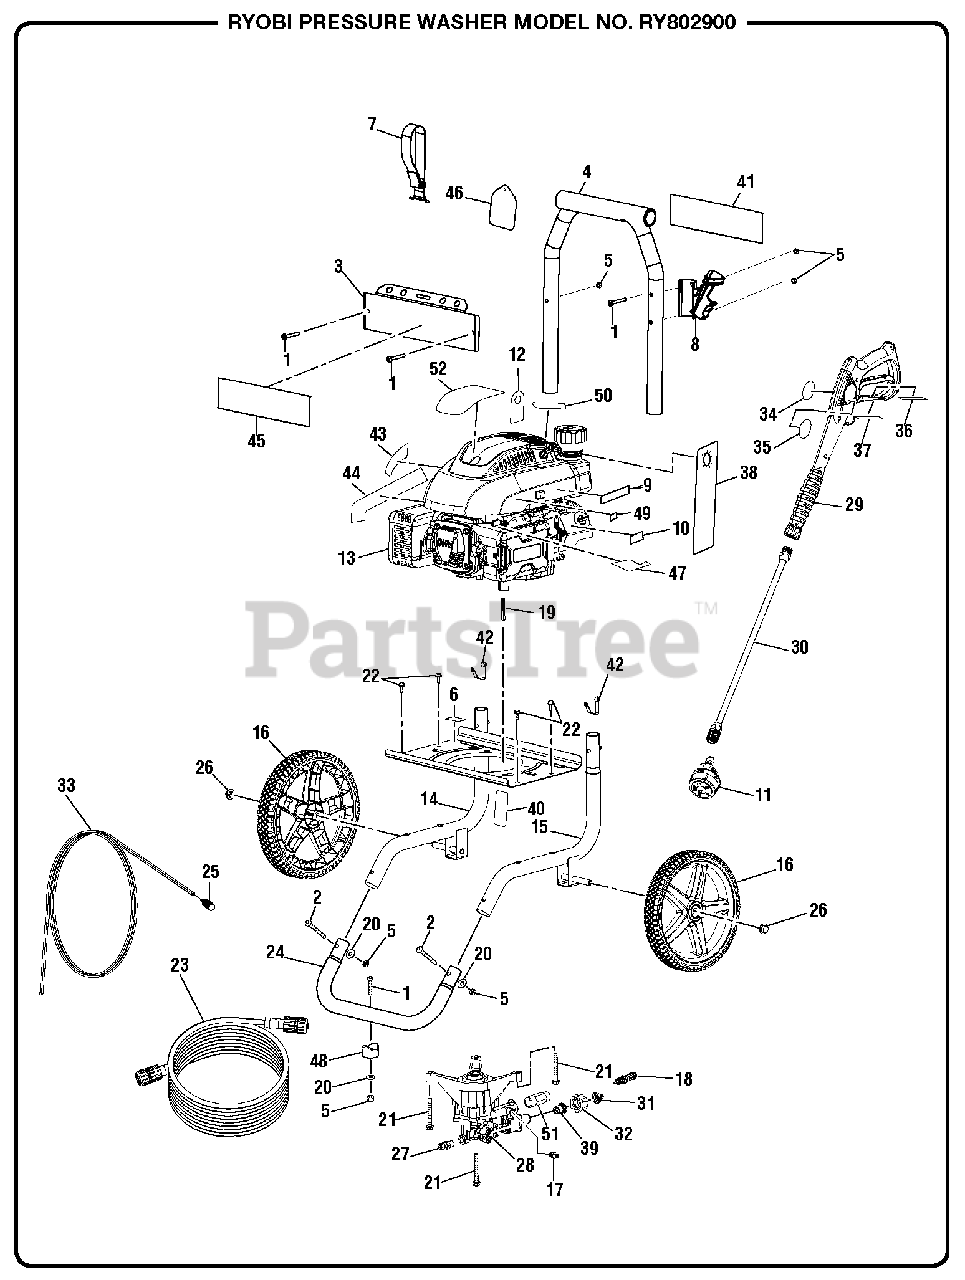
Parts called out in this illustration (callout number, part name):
1	Bolt (M6 x 48 mm, T30 Torx Pan Hd.)
2	Bolt (M6 x 42 mm, T30 Torx Pan Hd.)
3	Performance Panel
4	Handle w/Foam
5	Lock Nut (M6)
6	Add Oil Label
7	Hose Holder Strap
8	Wand Holder
9	Instruction Label
10	Fuel Valve Label
11	5-in-1 Nozzle
12	Oil Dipstick Hangtag
14	Main Frame Assembly
15	Main Frame Assembly
16	Wheel
17	Detergent Suction Kit
18	Pump Unloader Valve
19	Output Shaft Key
20	Washer (1/4 in.)
21	Bolt (M8 x 45 mm, Hex Flange Hd.)
22	Bolt (M6 x 16 mm, Hex Flange Hd.)
23	Hose (35 ft.)
24	Front Frame Assembly
25	Chemical Siphon Filter
26	Push Cap Nut (1/2 in.)
27	Thermal Release Valve
28	Pump
29	Trigger Handle Assembly
30	Extension Wand
31	Filter Screen (Pump Inlet)
33	Chemical Siphon Tube
34	Trigger Handle Logo Label
35	Trigger Handle Warning Label (Eng)
36	Trigger Handle Warning Label (Fr/Sp)
37	Trigger Handle Rating Label
38	Danger Hangtag
40	Combustion Label
41	Quick Start Label
42	Lock Button w/Spring Clip
43	Hot Surface Label
44	Danger Label
45	Performance Label
46	Nozzle Hangtag
47	Choke Label
49	Off Label
50	No E85 Label
51	Outlet Tube
52	Shroud Label
